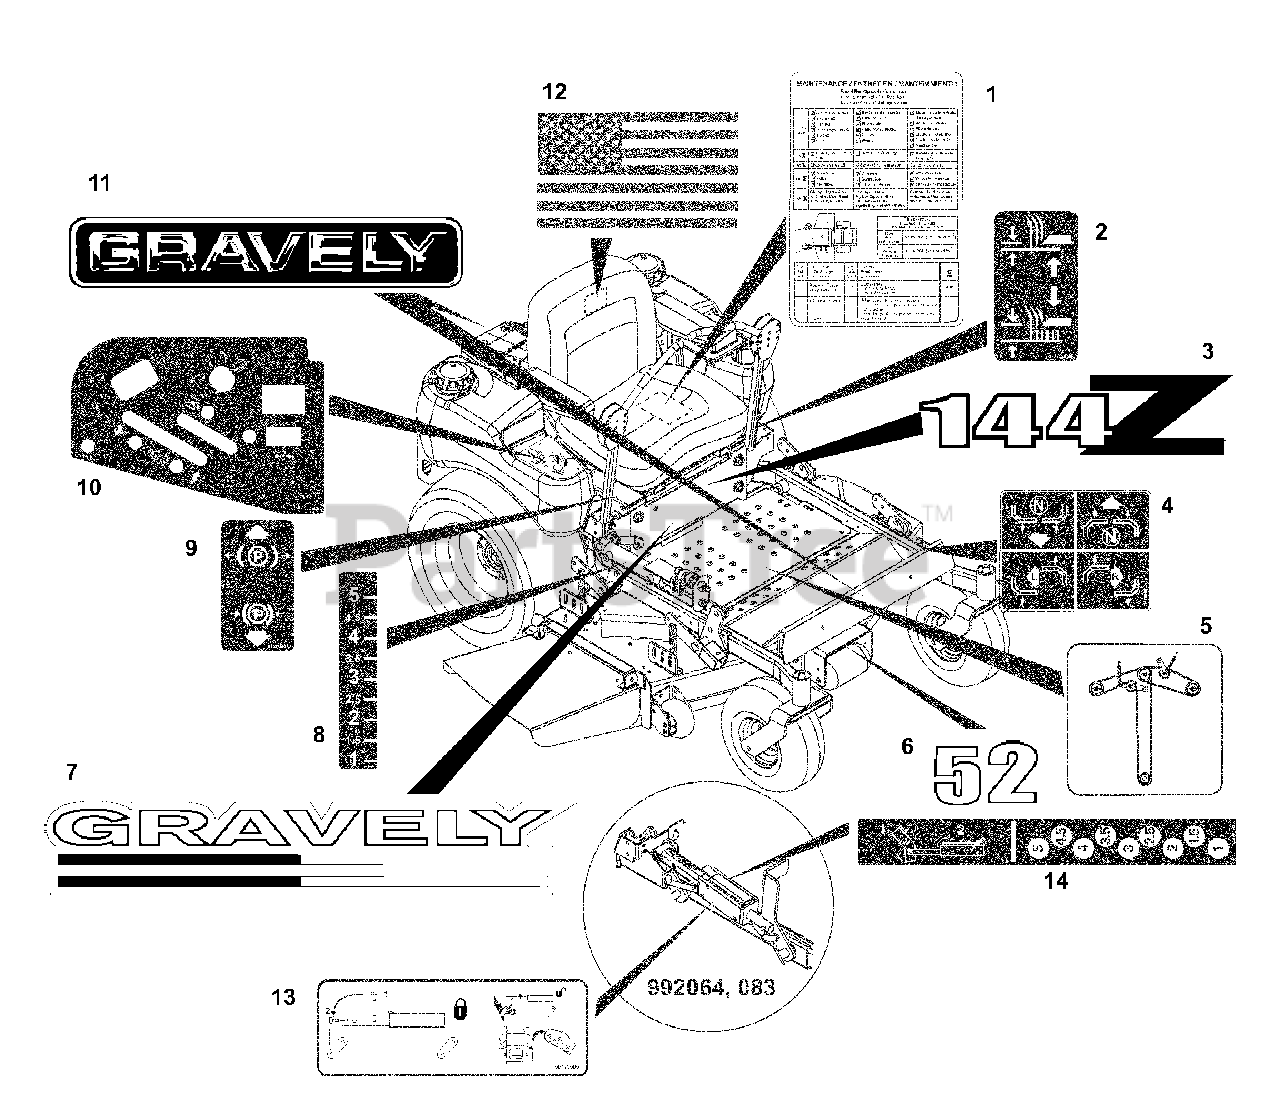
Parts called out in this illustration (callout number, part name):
1	Decal, Service Instructions
2	Decal, Lift Lever (077, 078, 079, 080, 081, 082, 310, 311)
3	Decal, PM 152Z (079, 081)
3	Decal, PM 144Z (064, 077, 083, 310)
3	Decal, PM 148Z (078. 311)
3	Decal, PM 160Z (080, 082)
4	Decal, Instructional Steering
5	Decal, Belt Diagram
6	Decal, 52 (079, 081)
6	Decal, 44 (064, 077, 083, 310)
6	Decal, 48 (078, 311)
6	Decal, 60 (080, 082)
7	Decal, ZT Hood
8	Decal, Height of Cut
9	Decal, Parking Brake Lever
10	Decal, Control Panel
11	Decal, 15" Gravely Logo
12	Decal, American Flag
13	Decal, Deck Service (064, 083)
14	Decal, Height of Cut (064, 083)
